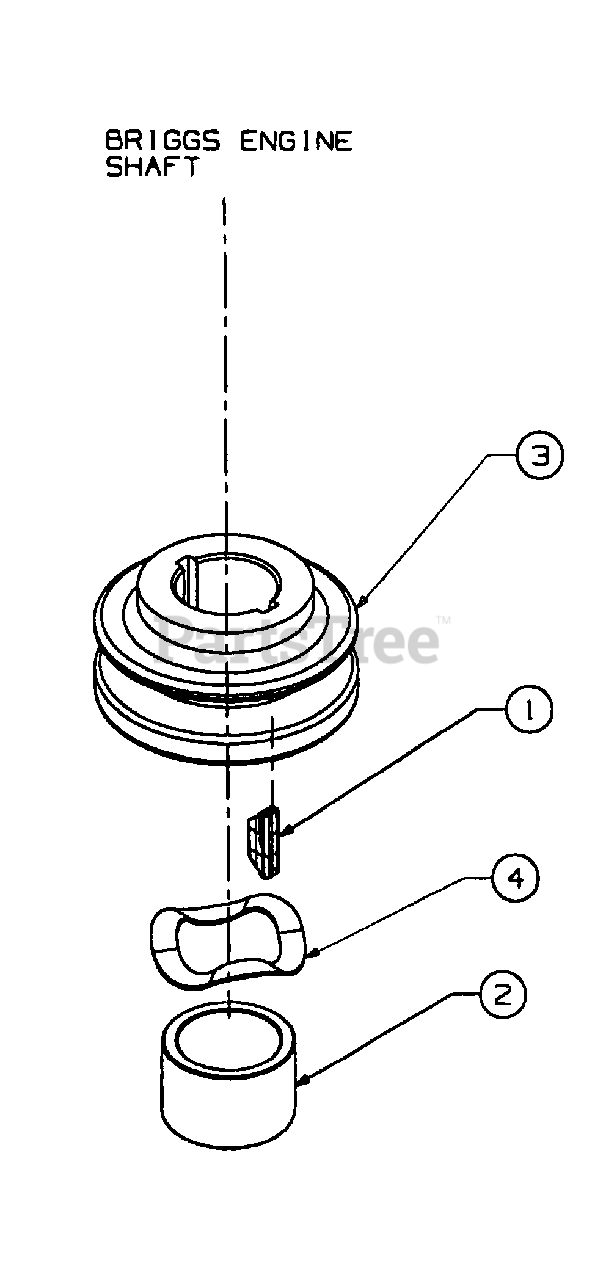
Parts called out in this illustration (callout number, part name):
1	KEY:HI-PRO 5/32 X 5/8
2	SPACER: .876 X 1.130 X .75
3	PULLEY:ENG:3/8V X 2.25 OD
4	WASH:WAVE: 1.38 OD X .88 ID X .02
